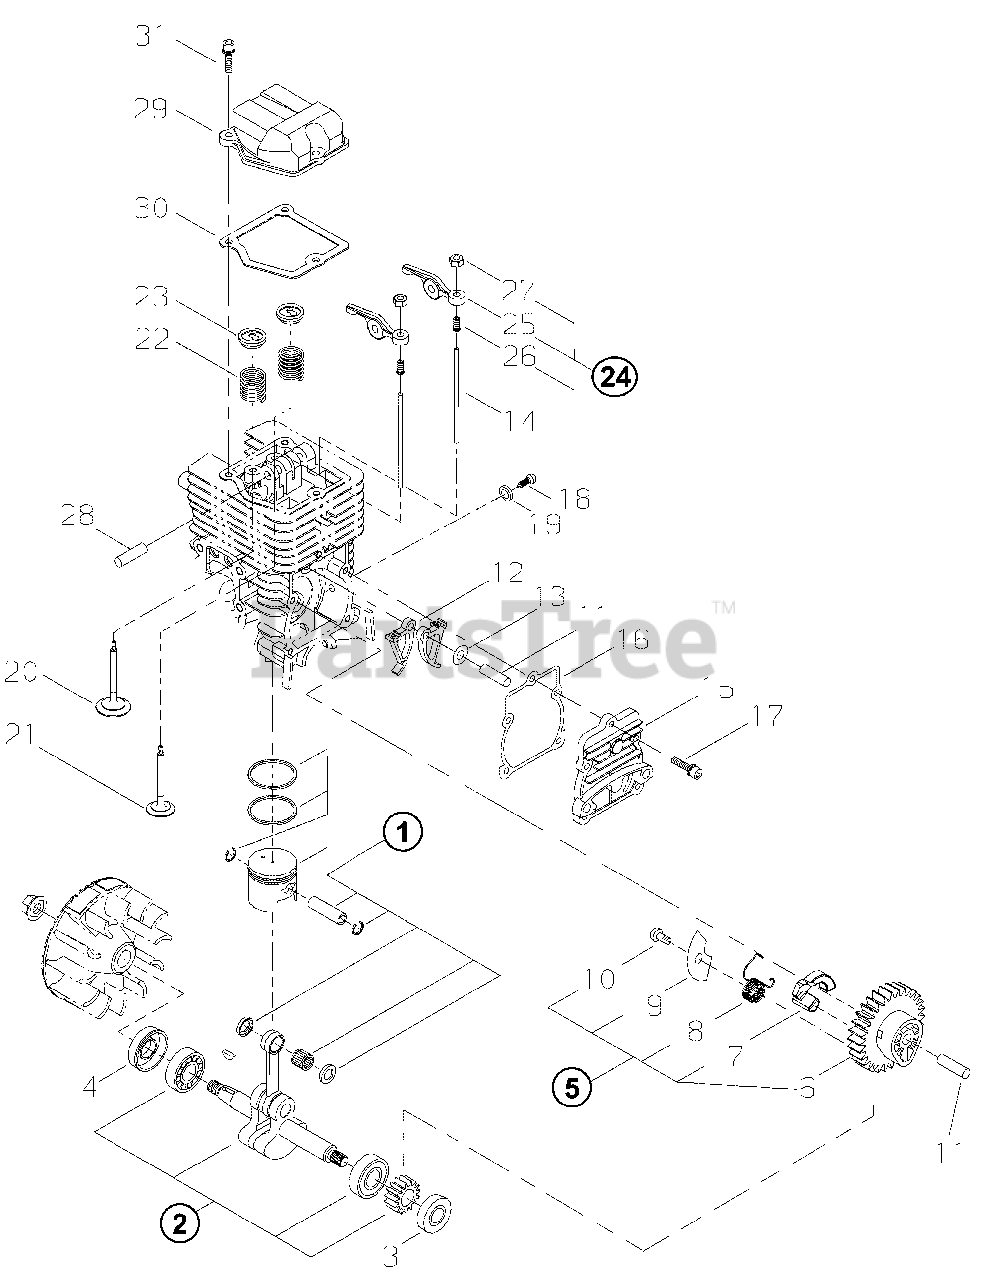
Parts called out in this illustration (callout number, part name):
1	PISTON KIT
2	CRANKSHAFT ASSY
3	SEAL, OIL 12
4	SEAL, OIL 12
5	CAM GEAR ASSY
6	GEAR, CAM
7	WEIGHT
8	SPRING
9	PLATE
10	SCREW, TAPPING 4×6
11	PIN, LOCATING Ø5×29.8 MM
12	FOLLOWER, CAM
13	WASHER 5 MM
14	PUSHROD
15	COVER, CAM GEAR
16	GASKET, CAM GEAR
17	BOLT M4×14
18	SCREW M5
19	WASHER Ø10ר5.5×2
20	VALVE, INTAKE
21	VALVE, EXHAUST
22	SPRING, VALVE
23	VALVE RETAINER ASSY
24	ARM ASSY, ROCKER
25	ARM, ROCKER
26	SCREW, ADJUSTER
27	NUT, ADJUSTER LOCK 5
28	SHAFT, ROCKER ARM Ø5×31.8 MM
29	COVER, ROCKER ARM
30	GASKET, ROCKER ARM
31	BOLT M4×12
